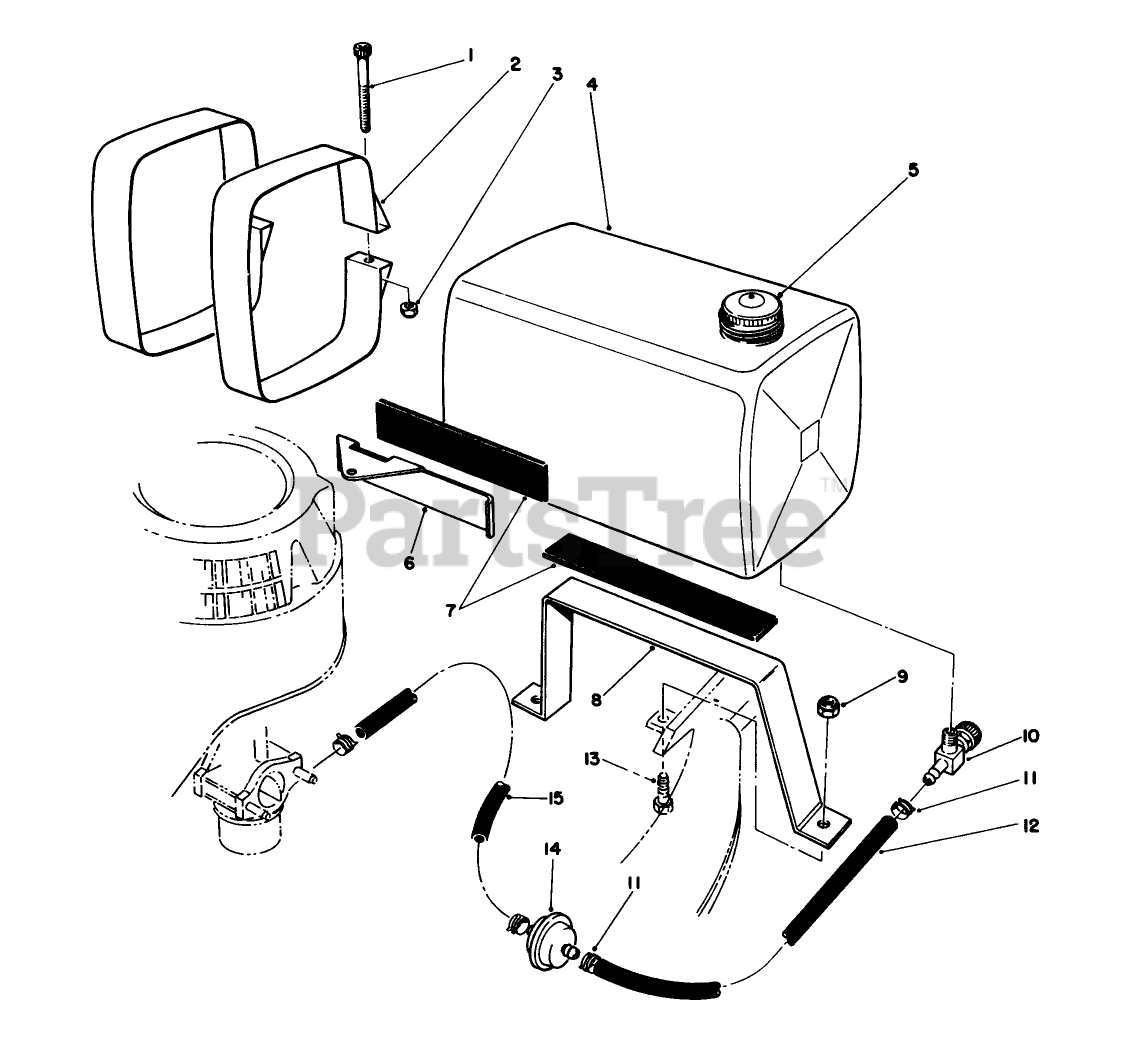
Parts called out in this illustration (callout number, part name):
1	SCREW-HSH
2	TANK STRAP WA
3	NUT-HEX
4	5 QT GAS TANK
6	FRT TANK MOUNT *
7	ISOLATOR PAD
8	TANK BOTTOM MOUNT *
9	NUT-LOCK, NI
11	CLAMP-FUEL LINE
12	HOSE-FUEL
13	SCREW-HH
14	FILTER-FUEL
15	HOSE-FUEL
